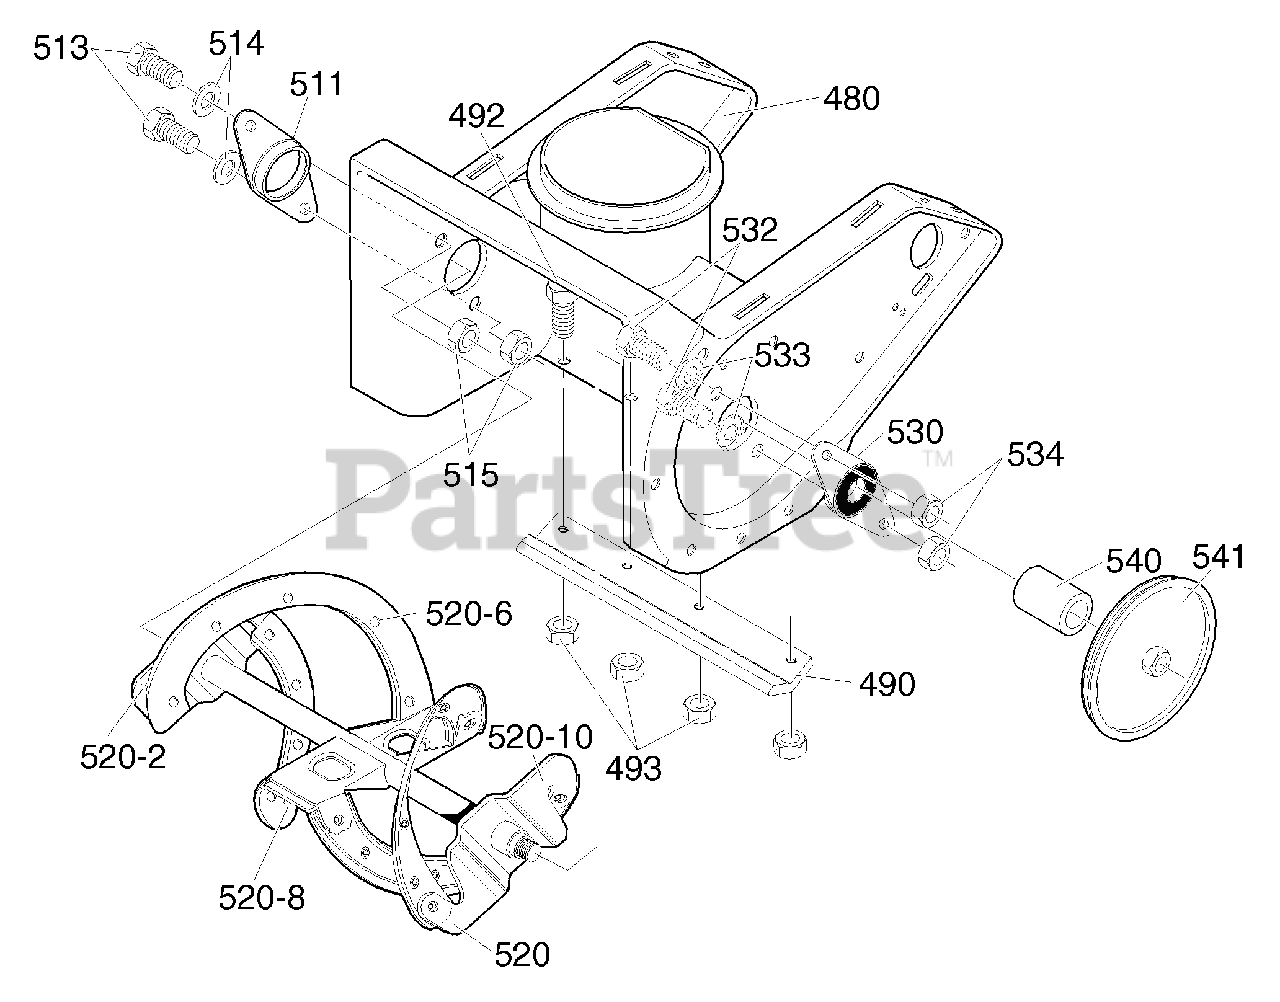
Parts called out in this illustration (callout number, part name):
480	HSNG, ASSY AUG 21"
490	BLADE, SCRAP 20.88 PLAST
492	SCREW, 1/4-20X .63 SLTRMA
493	NUT, 1/4-20 WDFL MAC-LOCK
511	BRNG, FL .670 ID X 1.25 OD X .88
513	SCREW, 1/4-20 X .88 HHC
514	WASHER, FLAT .281 X .63 X .65
515	NUT, 1/4-20 WDFL MAC-LOCK
520	AUGER, ASSY COMP 2CY 21"
530	BRNG & PLATE, ASSY
532	SCREW, 1/4-20 X .75 HMC
533	WASHER, FLAT .281 X .63 X .65
534	NUT 1/4-20 REGHEXCTRLK
540	SPACER, SLEV .640 X .88 X .732
541	PULLEY, V3L 6.00 X .75 20GA
